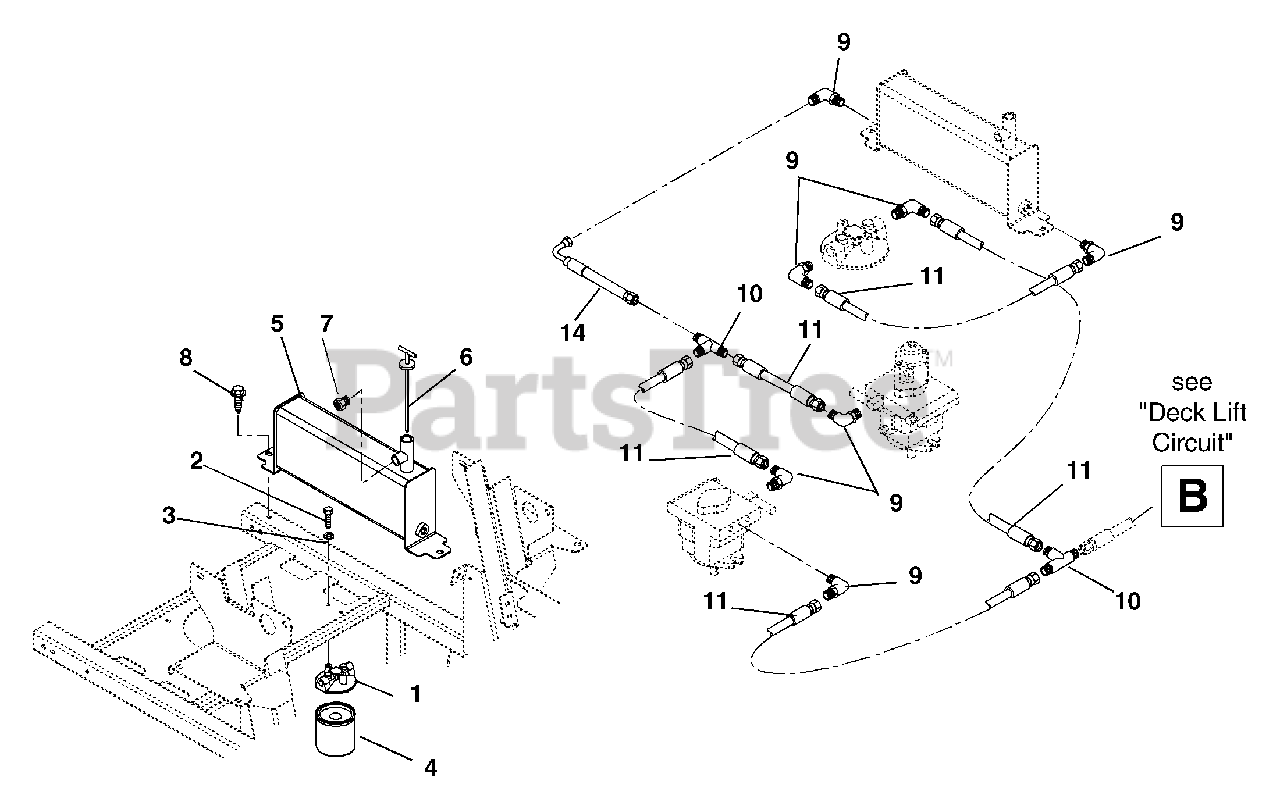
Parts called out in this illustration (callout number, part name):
1	HEAD, FILTER
2	@BLT-HEX .25-20X.50 GR5 YWZC
3	@WSHR-LK .25X.062 REG YWZC
4	ELEMENT, FILTER BE-40-0
5	TANK, HYDRAULIC WMT - ORANGE
6	DIPSTICK, HYDRAULIC TANK
7	PLUG, BREATHER 3/8"
8	@SCR-TAP .38-16X.75 HWH TR YWZ
9	ADPT 2503-6-6
10	ADPTR-PIPE (063T-6-6)
11	HOSE,HYD VALVE TO TANK
12	ADP 0503-4-6
13	ADPT 3903-6-6
14	HOSE, HYD .38-29-OK F6LO-F6J9
